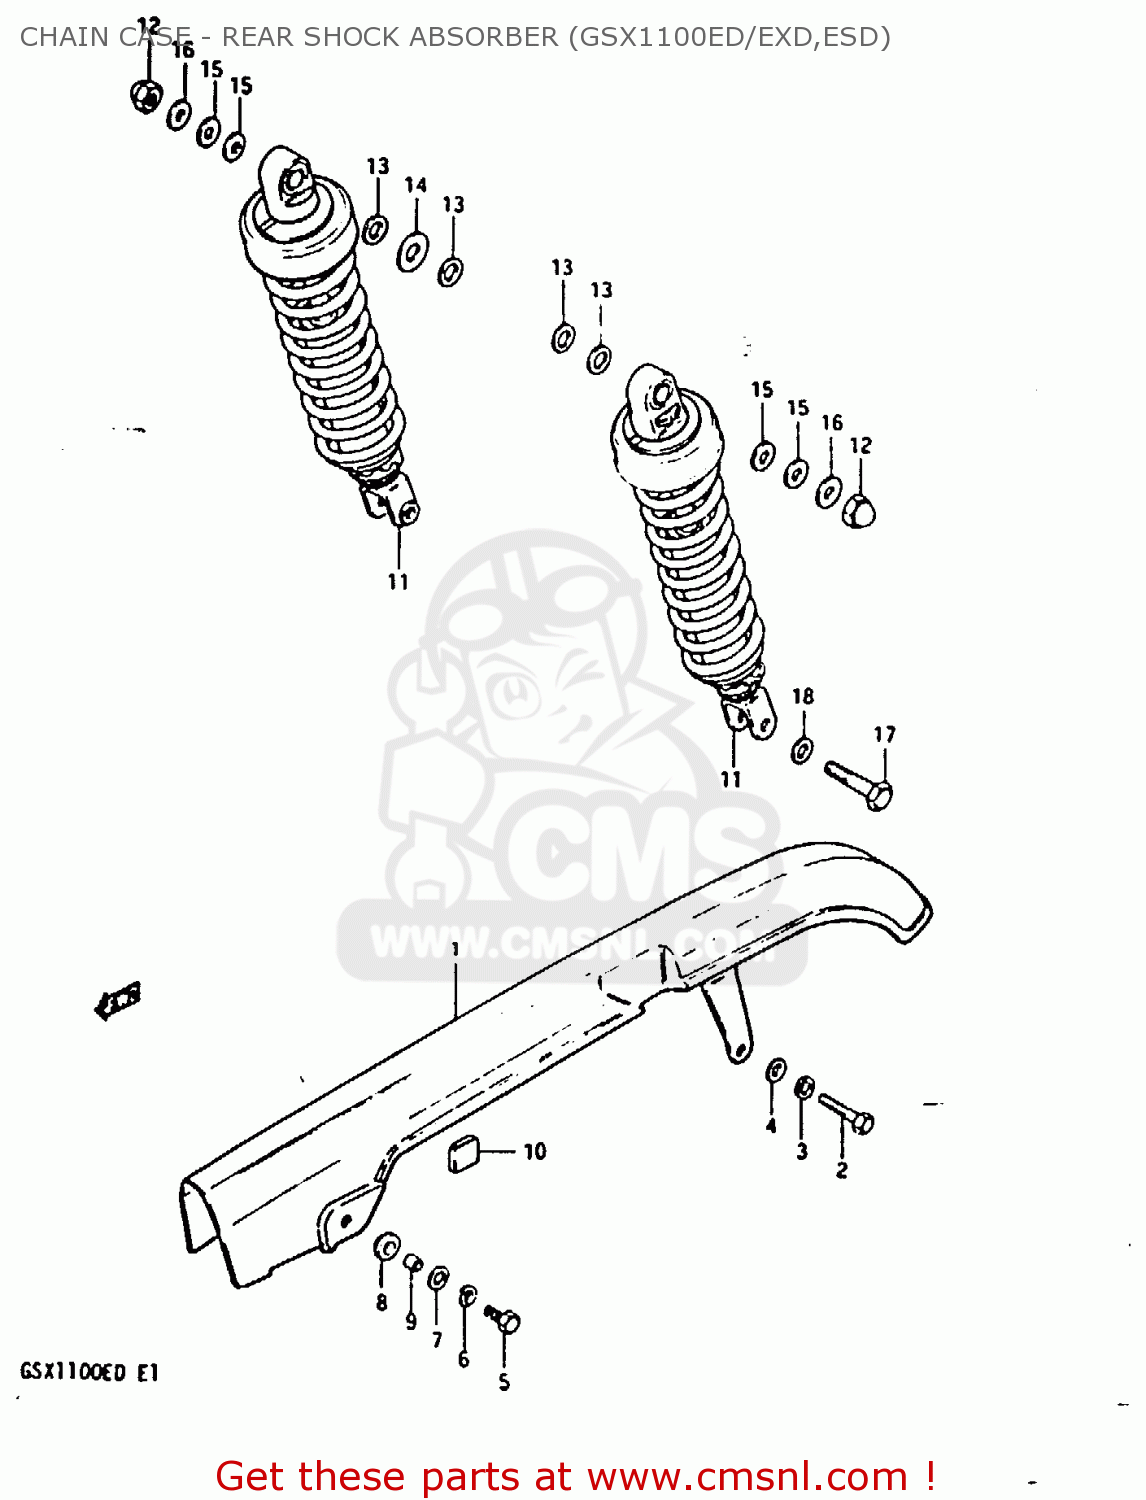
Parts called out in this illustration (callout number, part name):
1	CASE,CHAIN
2	BOLT
3	LOCK WASHER
4	WASHER
5	BOLT
6	LOCK WASHER
7	WASHER
8	CUSHION
9	SPACER(6.2X8.3X5.7)
10	CAP
11	SHOCK ABSORBER
12	NUT, LOWER LH
13	WASHER
14	WASHER (12.5X24X3.2)
15	WASHER
16	WASHER(10.5X24X3.2)
17	BOLT(10X36)
18	WASHER
